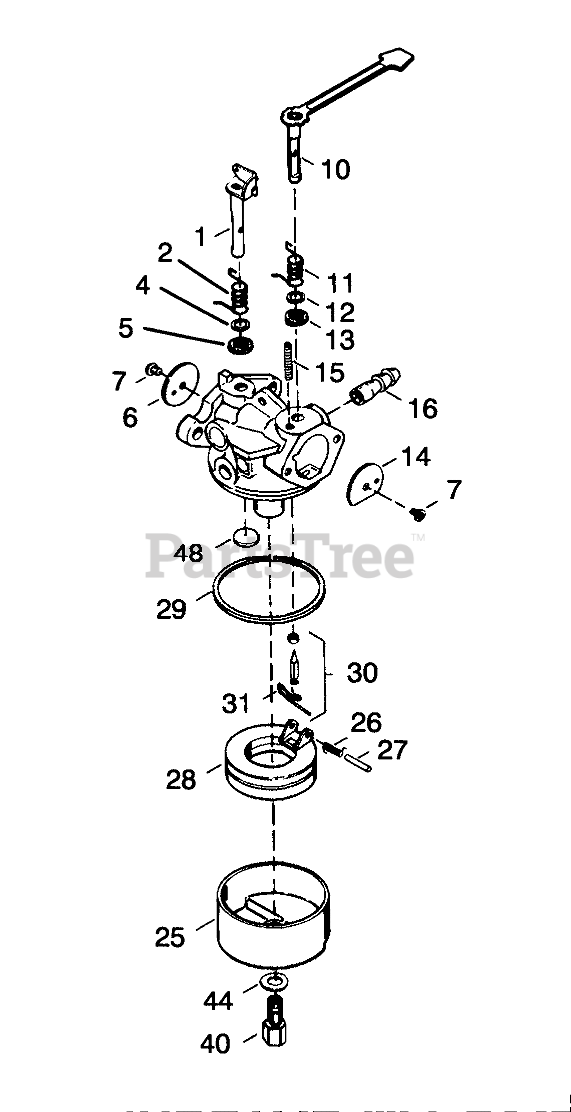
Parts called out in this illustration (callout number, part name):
1	Throttle Shaft & Lever Asm.
2	Spring-Trottle, Return
4	Washer-Seal, Dust
5	Seal-Dust
6	Shutter-Throttle
7	Screw-Shutter
10	Choke Shaft and Lever ASM
14	Shutter-choke
15	Spring-Positioning, Choke
16	Fitting-Fuel
25	Bowl Float
26	Spring-Float, Dampening
27	Shaft-Float
28	Float
29	O Ring-Bowl, Float
30	Inlet Needle, Seat & Clip (Incl. ref. #3)
31	Clip-Spring
40	Nut-Float Bowl
44	Gasket-Bowl
48	Plug-Welch, Atmospheric Vent
